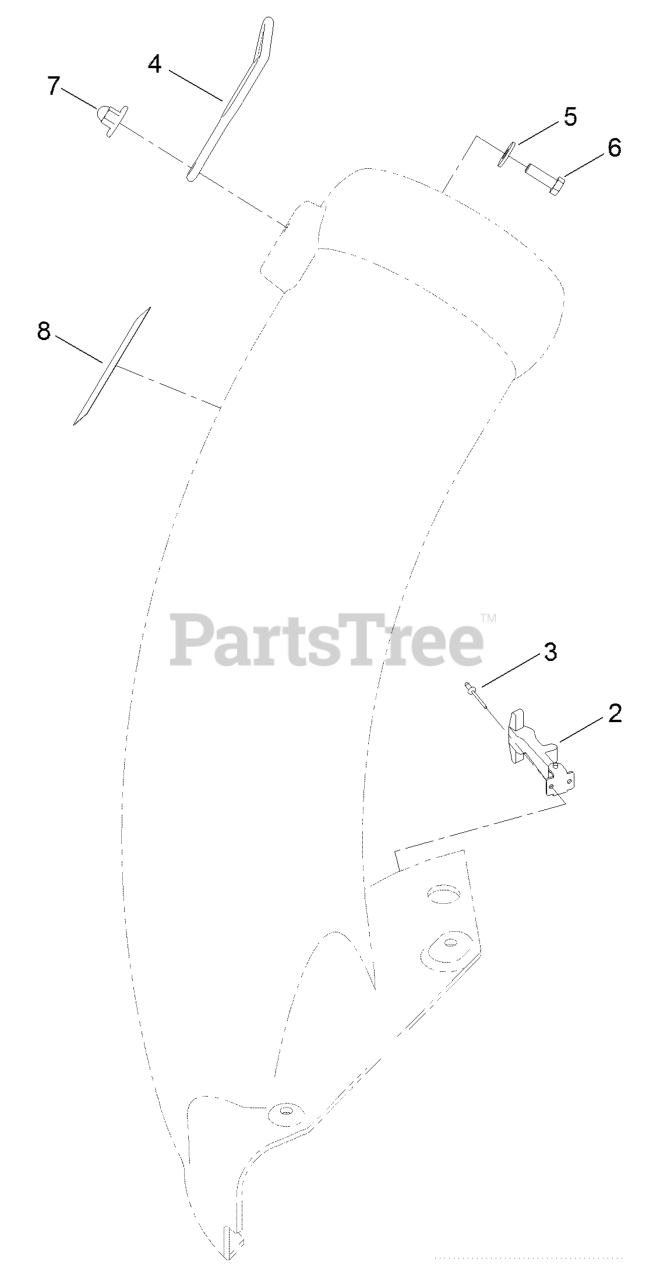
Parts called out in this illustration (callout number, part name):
2	HANDLE ASM
3	RIVET-POP
4	RETAINER-DUCT
5	WASHER-FLAT
6	SCREW-HH
7	NUT-IMPELLER
8	DECAL-DANGER
